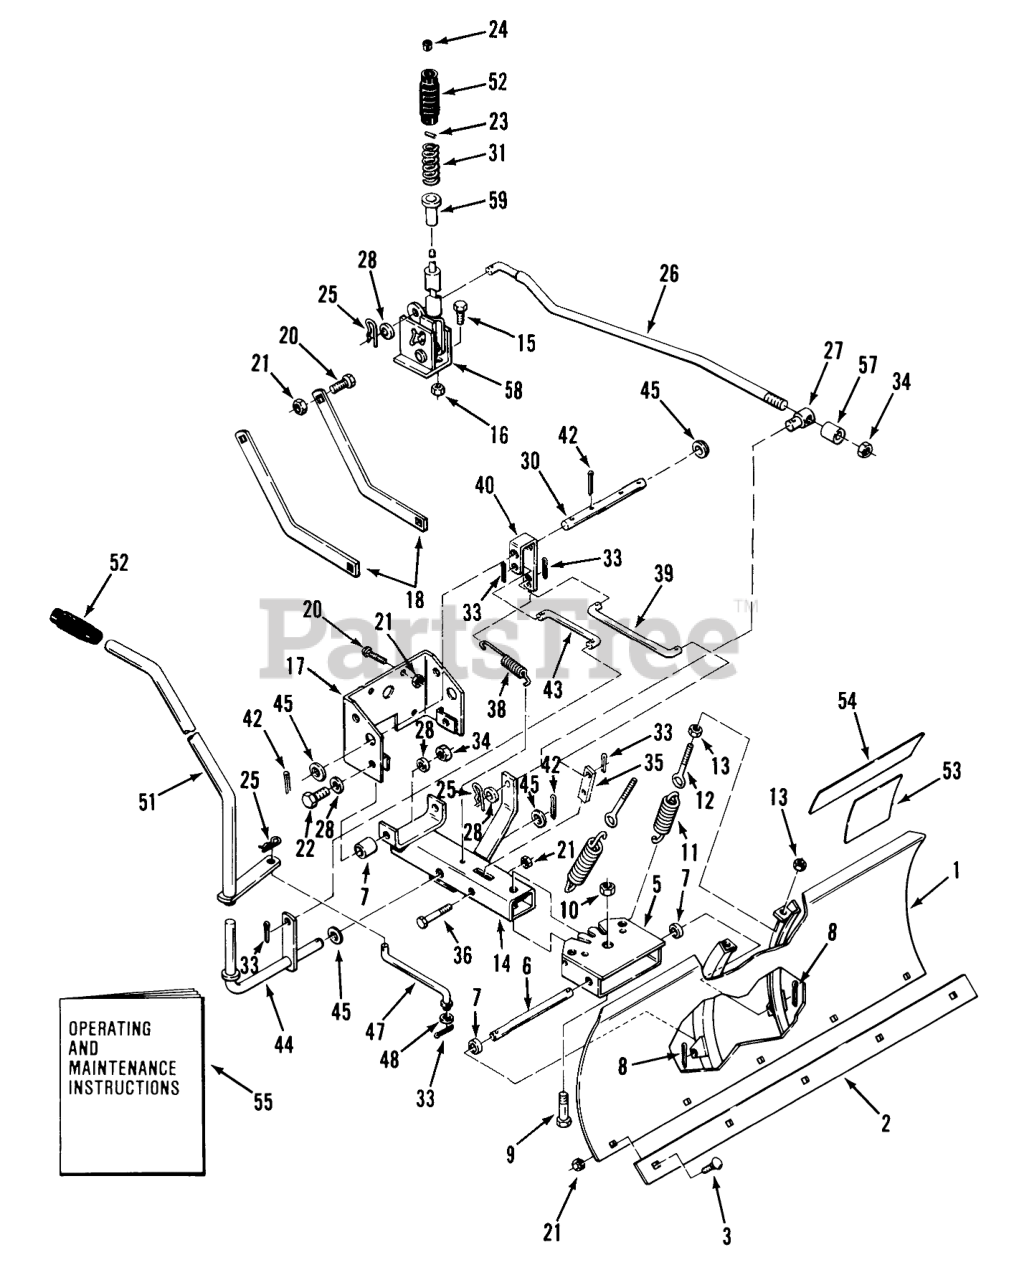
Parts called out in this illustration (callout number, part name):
1	Blade
2	Plate
3	Bolt-Carriage
5	ASS'Y-QUADRANT R
6	ROD-LOWER
7	Spacer
9	HEX HD CAP SCREW
10	Nut
11	SPRING
12	EYEBOLT
13	Nut
14	Frame
15	Bolt-Carriage
16	Nut
17	Front Support
18	BRACE R
20	Bolt
21	NUT
22	Hhcs
23	PIN-SPIROL
24	CAP-ROD, PLUNGER
25	Hairpin
26	ASS'Y-LIFT ROD
27	TRUNION
28	Washer
30	SHAFT R
31	SPRING-COMPRESSION
33	Pop Rivet
34	Nut
35	LATCH-QUADRANT R
36	HHCS
38	SPRING
39	ROD-LATCH
40	BELLCRANK-LATCH R
42	Cotter Pin
43	ROD-BELLCRANK
44	ASS'Y-HANDLE PIVO R
45	Washer
47	ROD-ANGLING
48	Washer
51	ASSY-HANDLE R
52	HANDGRIP
53	DECAL-DANGER
54	Decal
55	Operating and Maintenance Instructions
56	DECAL-OVERLAY
57	Spacer
58	ASS'Y-LIFT HANDLE R
59	RETAINER-SPRING
